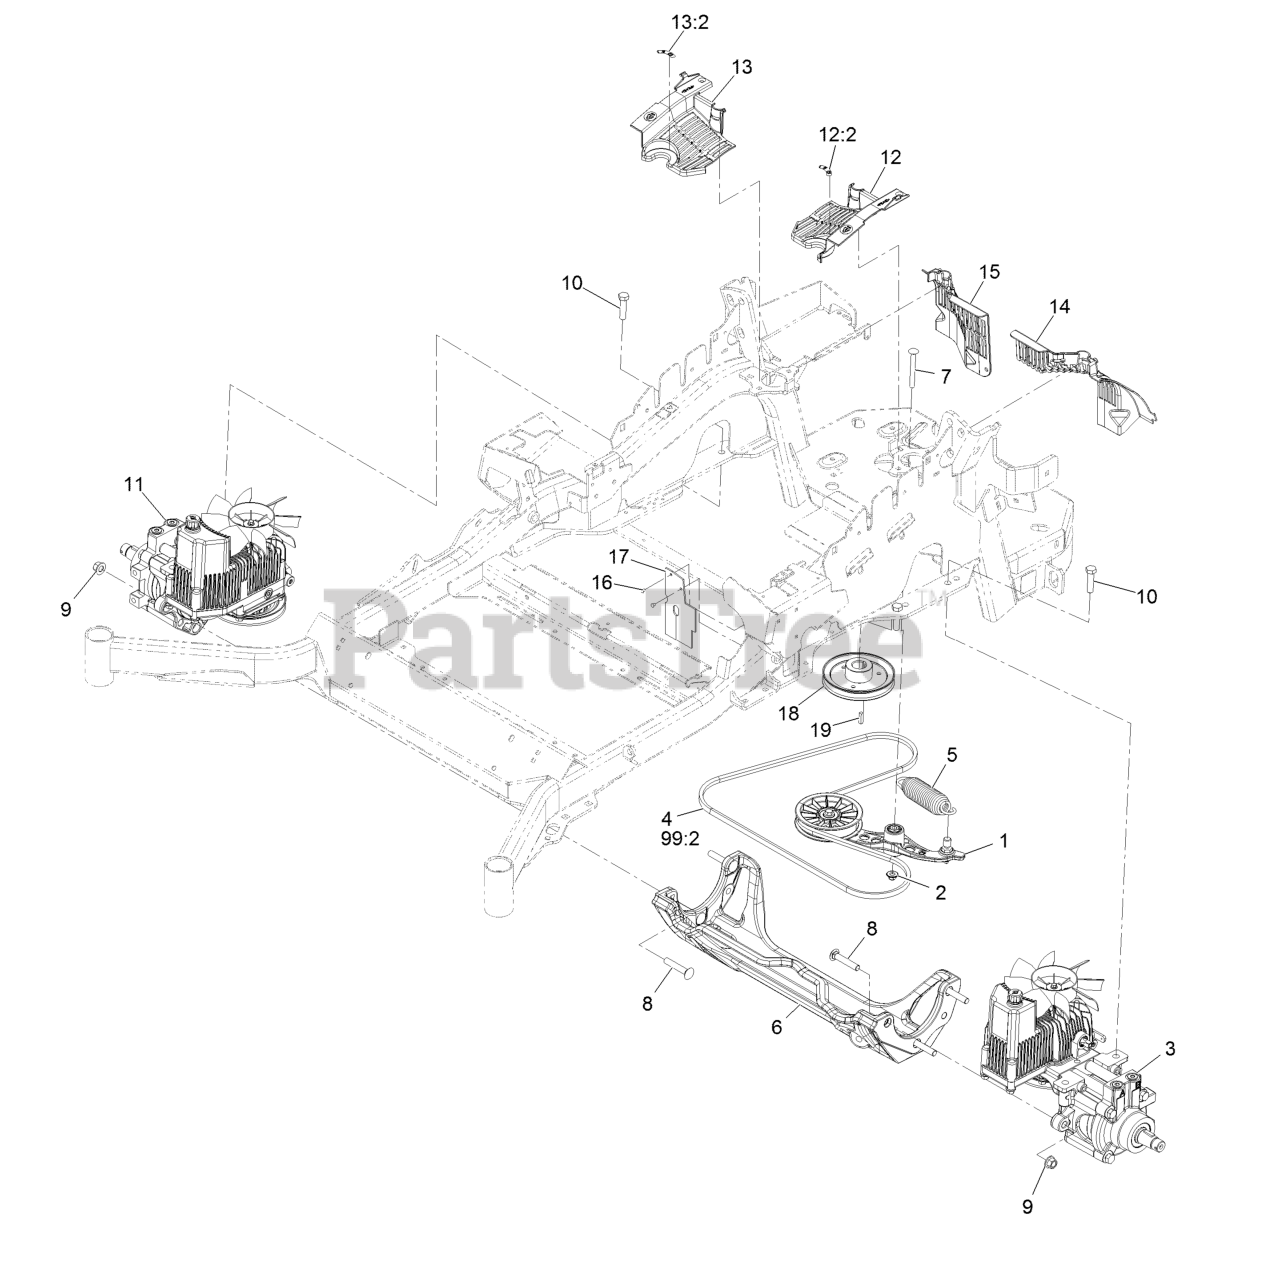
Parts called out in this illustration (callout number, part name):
1	Pump Idler ASM
2	Nut-Nyloc 3/8-16 Flg
3	LH Hydro ASM (16Cc W/Shock)
4	Belt
5	Spring-Extension
6	Cradle-Hydro
7	Bolt-Carriage Shoulder 3/8-16 X 3 1/2
8	Screw-CARR
9	Nut-Lock 1/2-13
10	Screw-HH 1/2-13 X 1 1/4
11	RH Hydro ASM (16Cc W/Shock)
12	LH Hydro Guard ASM
12:2	Decal-Oil, Hydro
13	RH Hydro Guard ASM
13:2	Decal-Oil, Hydro
14	Guard-Hydro Rear, LH Trim
15	Guard-Hydro, Rear (RH)
16	Rivet 3/16 X 1/4
17	Deflector-Air Flow
18	Sheave
19	Key-Machine 1/4 X 1/4 X 1
99	Bottle-Oil, 32Oz Hydraulic
99	Filter-Hydro
99	Bottle,Oil 1 Gallon Hydraulic
99	Kit, Hydro Service
99:1	Bottle-Oil, 32Oz Hydraulic
99:2	Belt
99:3	Filter-Hydro
